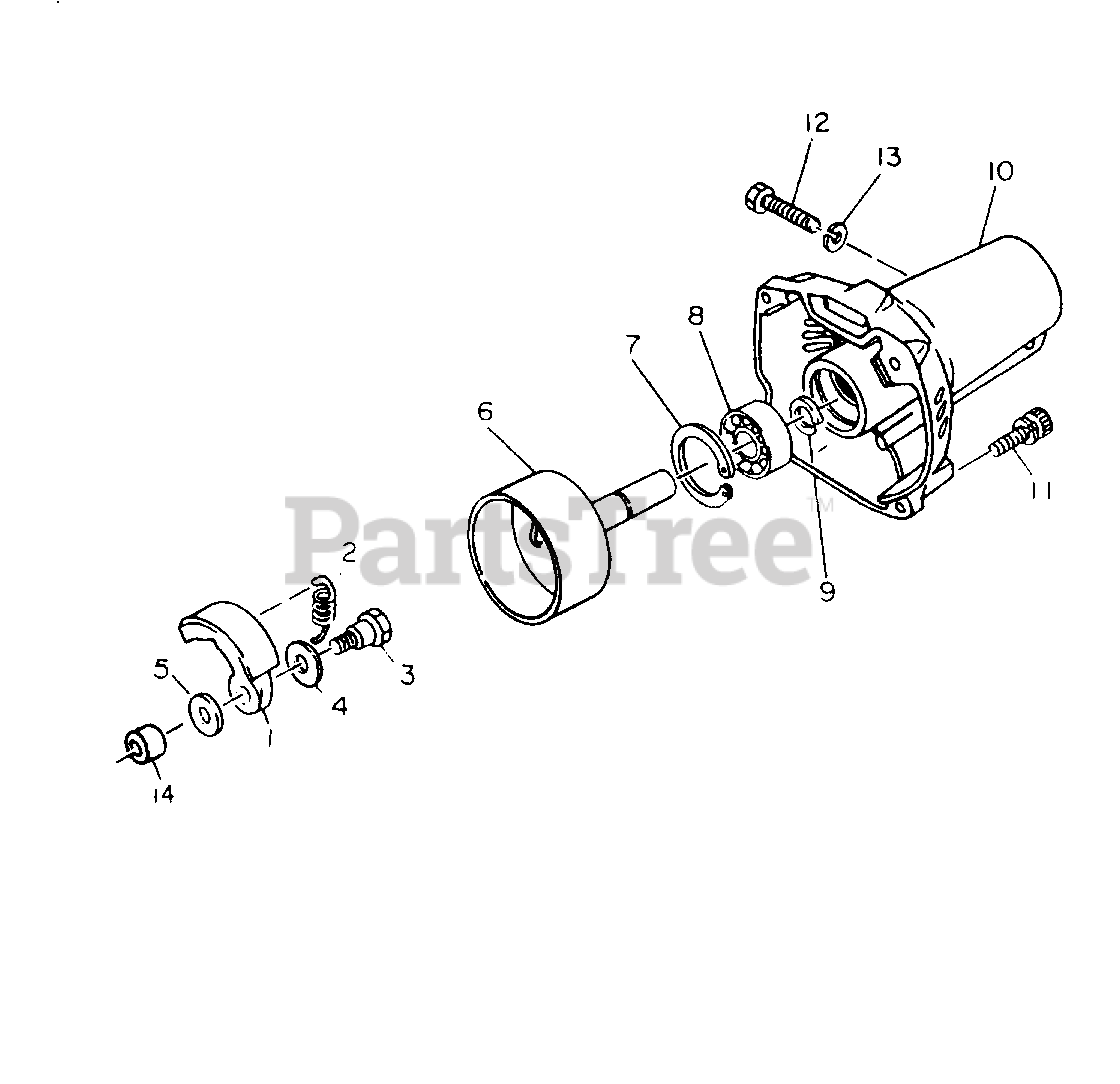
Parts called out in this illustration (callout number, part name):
6	Drum (Outside vendor part number)
7	Ring, Inner Retainer
8	Ball Bearing
9	Ring, Outer Retaining
10	Housing
11	Bolt, Socket Head
13	Washer, Spring
